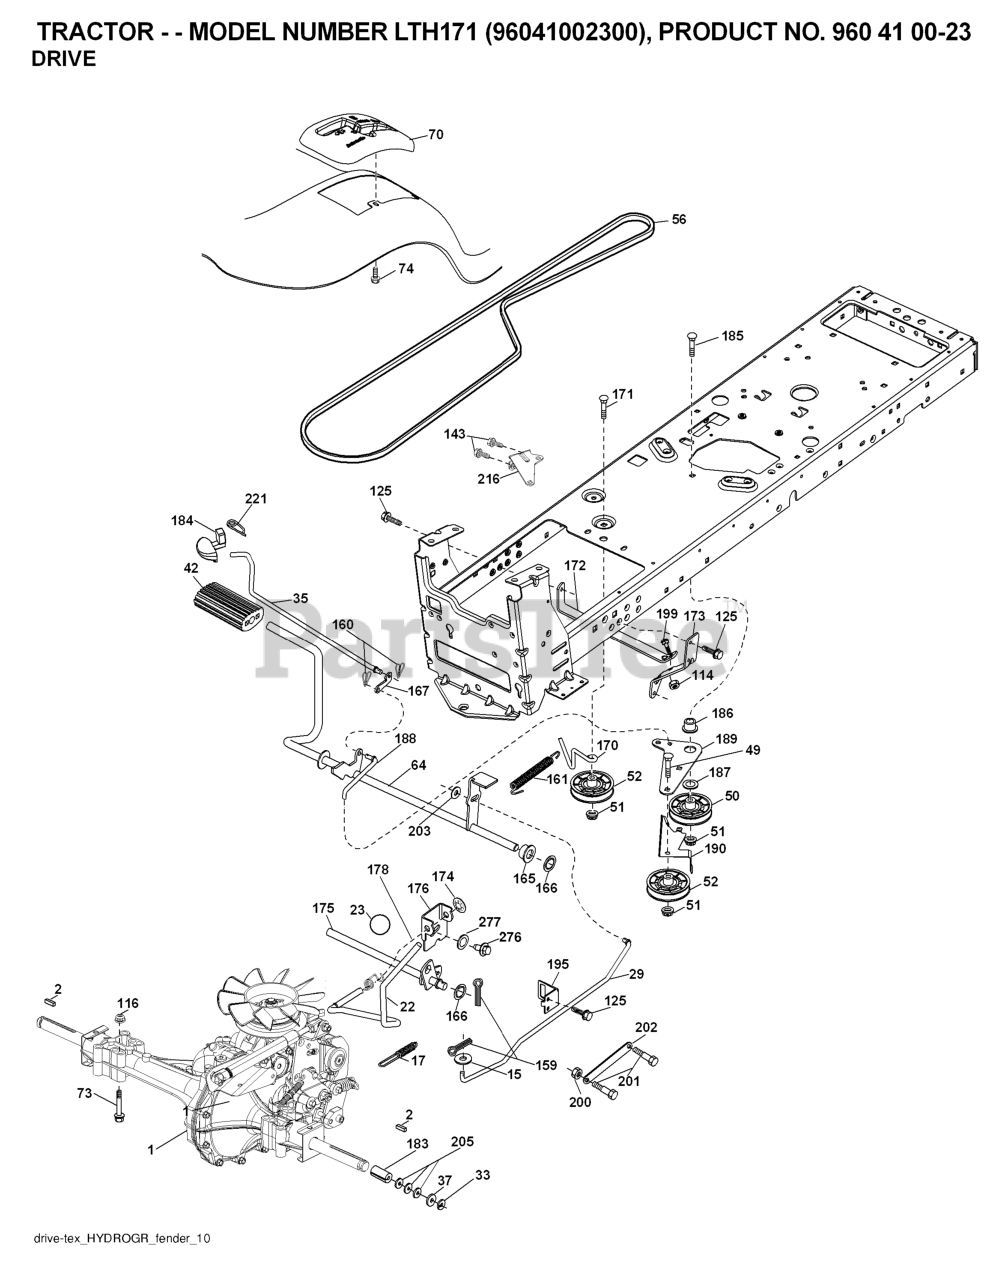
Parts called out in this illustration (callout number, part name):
2	SQUARE KEY
15	WASHER
17	SPRING.BRAKE.HG3000/3500
22	ROD.SHIFT.FENDER.TLT.2006
23	KNOB.DUCKHEAD.1/2
29	ROD.BRAKE.HG-0510
35	ROD.CNTRL.PARK.PREDATOR.LT.TEX
42	PEDAL COVER T
50	IDLER.FLAT.910.OFFSET
51	NUT LOCK FLG 3/8-16 UNC
52	IDLER.V-GROOVE.910.OFFSET
64	SHAFT.ASM.PEDAL.BRAKE.
70	CONSOLE SHIFT
73	BOLT HEX 5/16-18 GR 5
74	SCREW.HI-LO.CONSOLE
114	NUT.71038.31-18.HEX.NYLOCK
116	NUT LOCK HEX FLANGE 5/16-18
125	SCREW
143	Screw 5/16-18 x 1/2 Hex, Self Tapping 5/16-18 x 1/2
159	COTTER PIN
160	RETAINER CLIP
161	SPRING.RETURN.CLUTCH.2006
165	BUSHING.SHAFT.BRAKE.HAND
166	NUT.PUSH.625.2006
167	LATCH.BRAKE.SPRING
170	KEEPER.V-IDLER.CENTER.
172	STRAP.TRQ.LH.FS.HG0510
173	STRAP TORQUE RH
174	NUT.PUSH.500.2006
175	SHAFT.ASM.SHFT.HG0510/
176	ARM.CLEVIS.ROD.SHIFT
178	SPRING.SHIFT.GT2006
183	SPACER AXLE
184	HANDLE PARKING BRAKE
186	SPACER.RETAINER
187	WASHER 12/32X2X10GA
188	RP.LINK.CLUTCH.GROUND.DRIVE
189	BELLCRANK.GROUND.DRIVE.TEX.
190	KEEPER.BELLCRANK.DRIVE
195	BRKT.ROD.BRAKE.18/20/2
200	NUT.CENTERLOCK.5/16-
201	BOLT SHOULDER 5/16-18 UNC
203	WASHER
216	BRACKET.PULLEY.IDLER.W/TEX
221	RETAINER.SPRING.CLIP.H
276	BOLT FIN HEX 7/16-14 X 1
277	WASHER SERRATED
